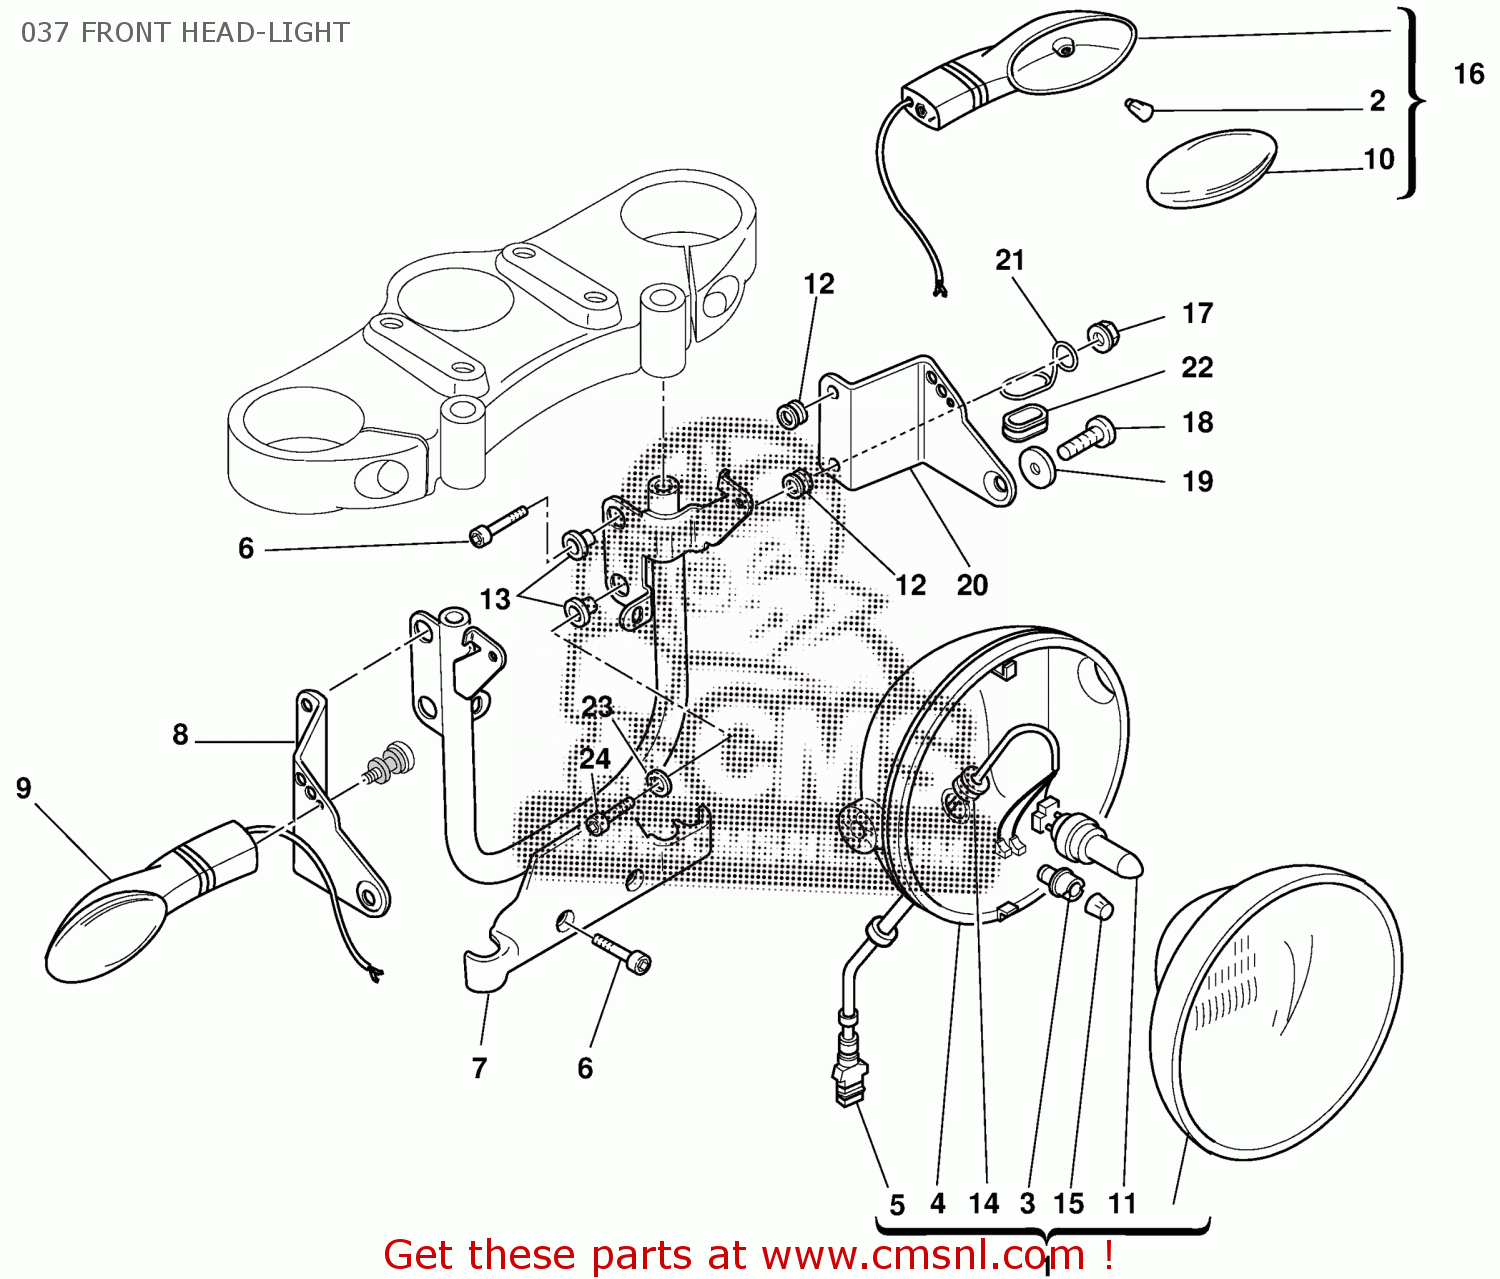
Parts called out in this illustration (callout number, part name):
1	HEADLIGHT
2	BULB 12V 10W BA15S
3	BULB SOCKET
4	HOUSING, HEADLAMP
5	HEAD LIGHT WIRING HARNESS
6	BOLT, SOCKET HEAD M6X20
7	BRACKET, HEADLIGHT
8	HOLDER, FLASHER LIGHT RH
9	FRONT FLASHER LIGHT, RIGHT
10	LENS FLASHER LIGHT
11	BULB 12V 55/60W HALOGEN H4
12	RUBBER PAD
13	SPACER
14	FAIRLEAD
15	BULB 12V 4W
16	FRONT FLASHER LIGHT, LEFT
17	SELF LOCKING NUT M6 H5.5
18	SCREW M8X25
19	RETAINER
20	HOLDER, FLASHER LIGHT LH
21	RING
22	FAIRLEAD
23	WASHER
24	BOLT, SOCKET HEAD M6X25
